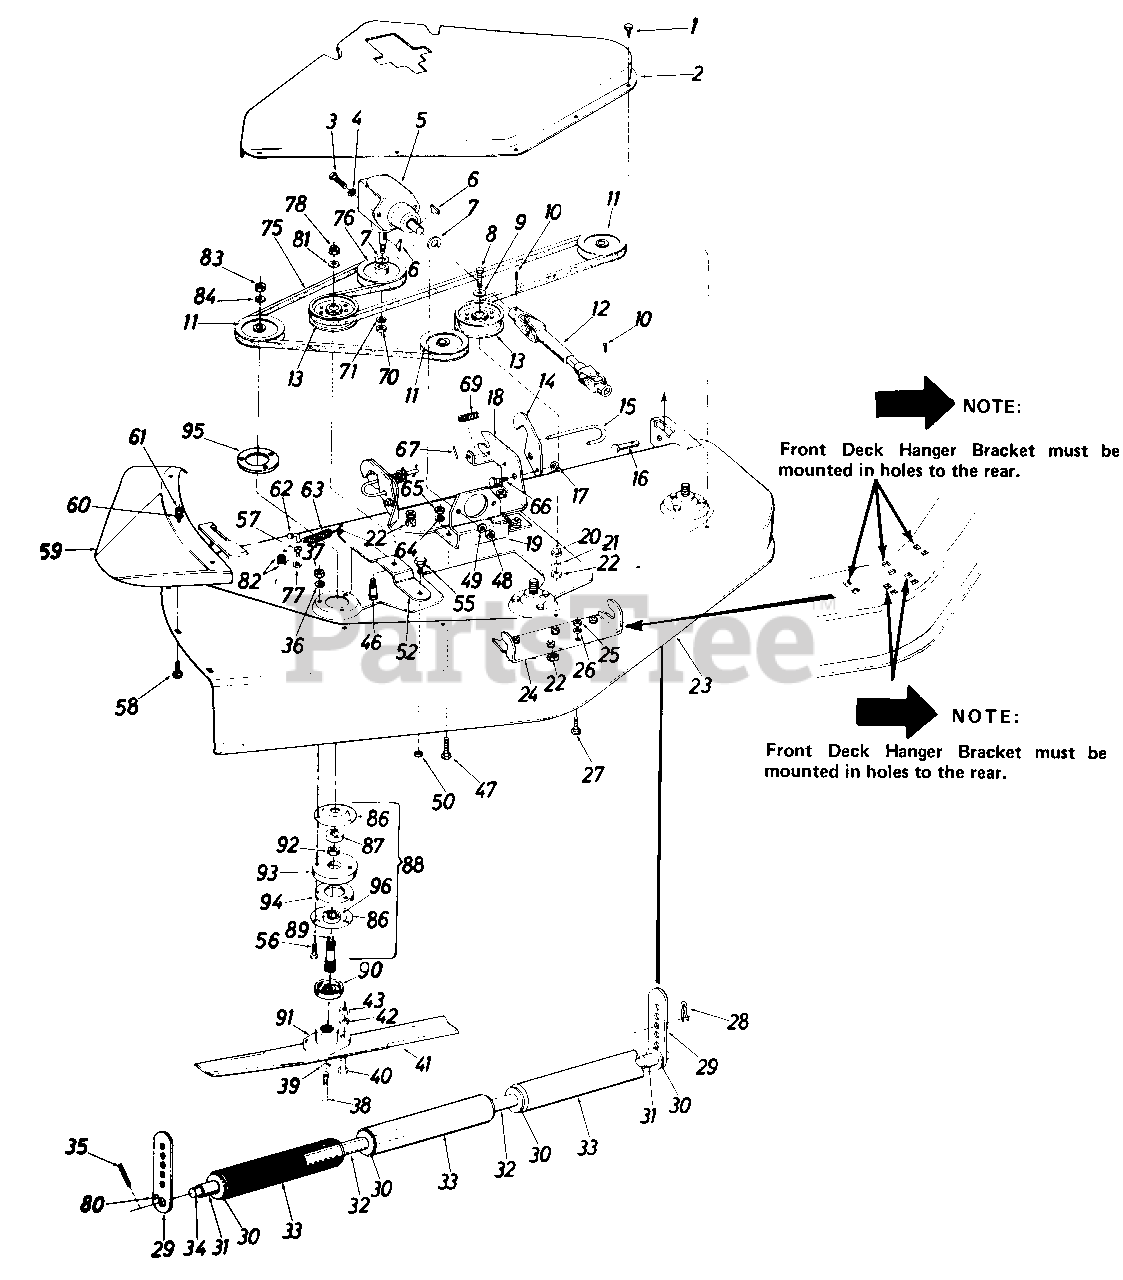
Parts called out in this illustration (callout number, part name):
1	Hex B Tap Scr. 1/4-20 x .38" Lg.
4	Ext. L-Wash. 3/8" Scr.*
5	Right Angle Drive
6	#9 Hi-Pro Key 3/16 x 3/4" D ia.
7	Fl-Wash. 29/32 I.D.
8	Hex Scr. 3/8 16 x 2.25" Lg.*
9	Fl-Wash. 3/8" I.D.
10	Sq. Hd. Set Scr. 3/8-16 x .50" Lg. Cup
11	Deck Pulley
12	Universal Drive Shaft Ass'y.
13	Deck Idler Pulley
14	Hanger Lock
15	Release Pin
16	Clevis Pin .500 Dia.
17	Hex Cent. L-Nut 5/16-18 Thd.
21	L-Wash. 3/8" Scr.*
22	Hex Nut 3/8-16" Thd.*
26	L-Wash. 5/16" Scr.*
27	Carriage Bolt 5/16-18 x 1.00" Lg.*
28	Internal Cotter Pin
30	Fl-Wash. .75 I.D. x 1.5 O.D.
31	Spacer .758 I.D. x 1.25 O.D. x . 530
34	Roller Shaft
35	Roll Pin 3/16 x 1.25
36	L-Wash. 5/16" Scr.*
37	Hex Cent. L-Nut 5/16-24 Thd.
38	Hex Scr. 3/8-24 x .75" Lg. Thd. Rolling
39	L-Wash. 3/8" Scr. H.D.
40	Hex Scr. 5/16-24 x l.OO" Lg.
41	Blade 17"
42	L-Wash. 5/16" Scr.*
43	Hex Cent. L-Nut 5/16-24 Thd.
46	Hex Scr. 5/8-18 x 1.31" Lg.
47	Carriage Bolt 5/16-18 x .75"
48	Hex Nut 3/8-16 Thd.*
49	L-Wash. 3/8" Scr.*
50	Hex Cent. L-Nut 7/16-14
56	Hex Scr. 5/16-24 x 1.50" Lg. Grade 5
57	Hex Nut 1/4-20 Thd.*
58	Carriage Bolt 5/16-18 x .75 Lg.*
60	L-Wash. 5/16" Scr.*
61	Hex Nut 5/16-18 Thd.*
62	Hook Bolt
63	Extension Spring
64	L-Wash. 5/16" Scr.
65	Hex Nut 5/16-18 Thd.*
66	Shld. Scr.
67	Roll Pin 1/8" Dia.
69	Compression Spring
70	Hex Cent. L-Nut 5/8-18 Thd.
71	L-Wash. 5/8" Scr.*
75	"V"-Belt A Sect. 117" Lg.
76	Drive Pulley
77	Hex Cent. L-Nut 1/4-20 Thd.
78	Hex Cent. L-Jam Nut 5/8-18 Thd.
80	Spring Pin Spiral 1/4" Dia. 1.00" Lg.
81	Fl-Wash. .62" I.D.
82	Ext. L-Wash. 1/4" Scr.*
83	Hex Jam Nut 5/8-18 Thd.
84	L-Wash. 5/8" I.D.*
86	Bearing Housing
87	Ball Bearing
88	Deck Spindle Ass'y.
89	Spindle
90	Bearing Shield
91	Blade Adapter
92	Spacer
93	Spindle Spacer Plate
94	Reinforcement Plate
95	Spindle Reinforcement Plate
96	Open Bearing Housing
12649-0638	GUARD-CHUTE - MTD/TROY-BILT RED (0638)
12649-0648	GUARD-CHUTE - TECH GRAY (0648)
12650-4008	Height Adjuster - WINE RED (4008)
